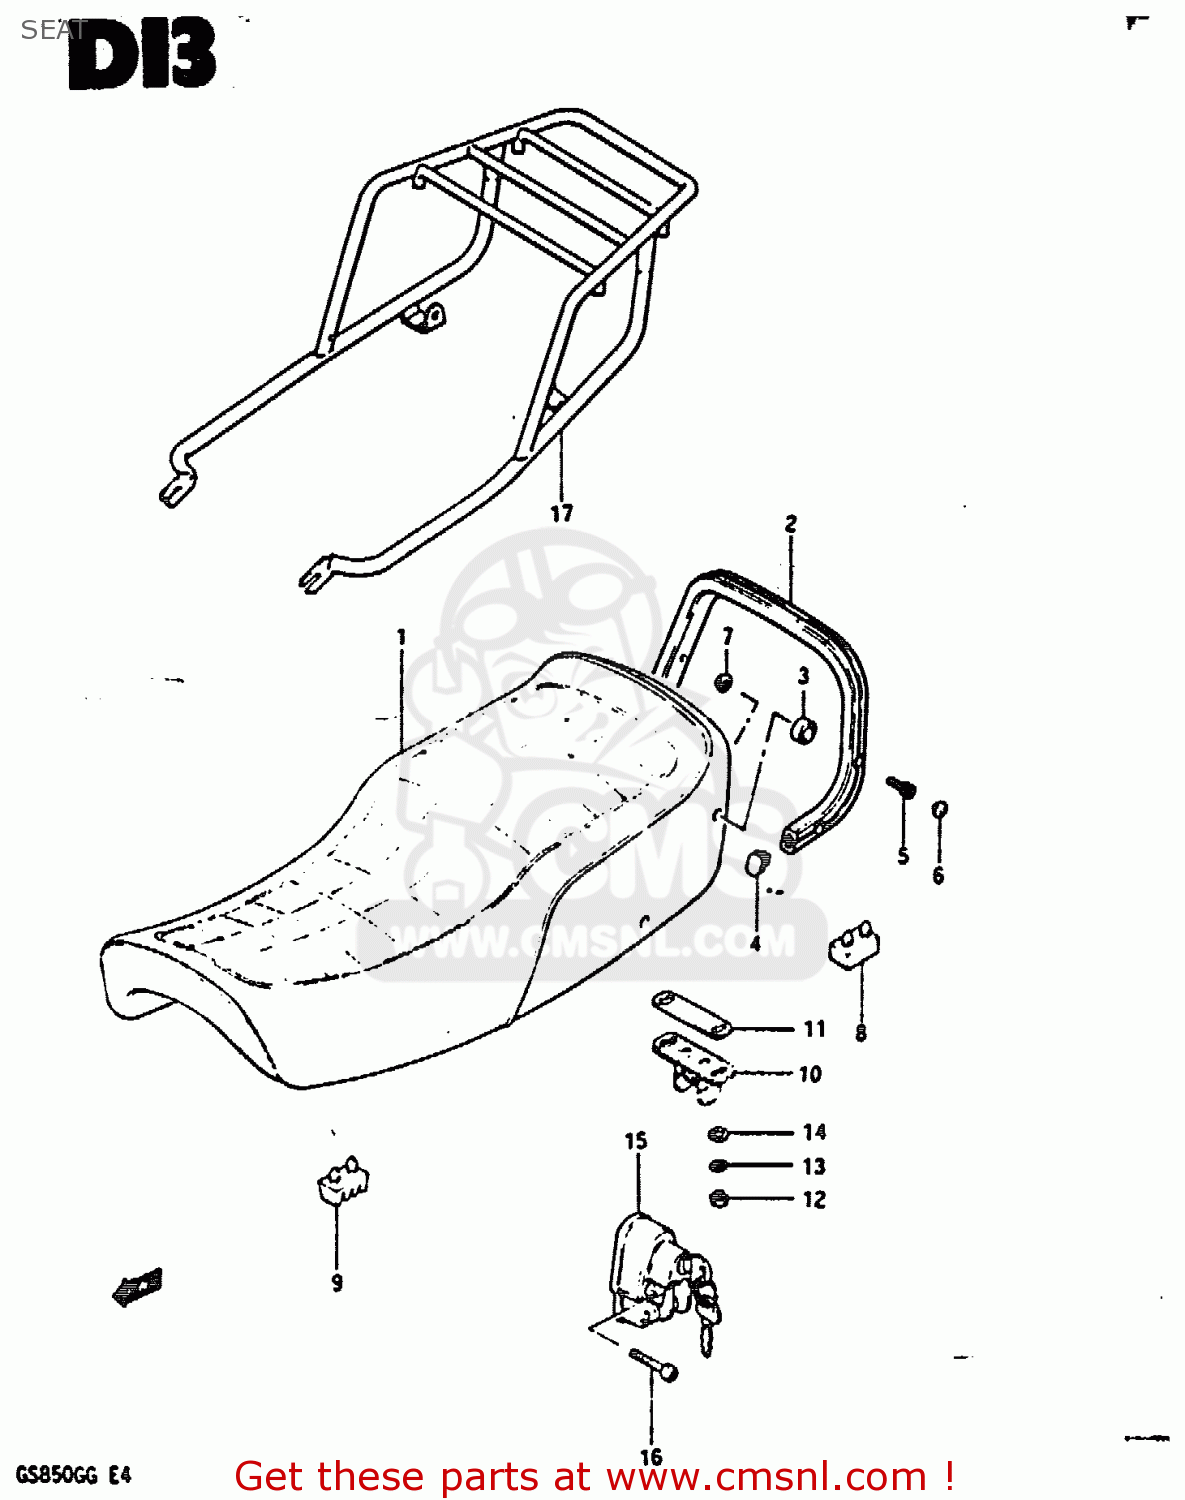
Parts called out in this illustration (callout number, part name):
1	SEAT (BLACK)
2	HANDLE,PILLION RIDER
3	SPACER,REAR
4	END,PILLION RIDER HAND
5	BOLT, REAR (8X30)
6	CAP(OD:14.5)
7	NUT
8	CUSHION(40X23X12.7)
9	CUSHION,SUPPORT(50X25X32)
10	STRIKER,SEAT LOCK
11	SHIM,SEAT LOCK STRIKER
12	NUT
13	WASHER,LOCK
14	WASHER
15	LOCK ASSY,HELMET
16	BOLT
17	CARRIER, SPORTS
